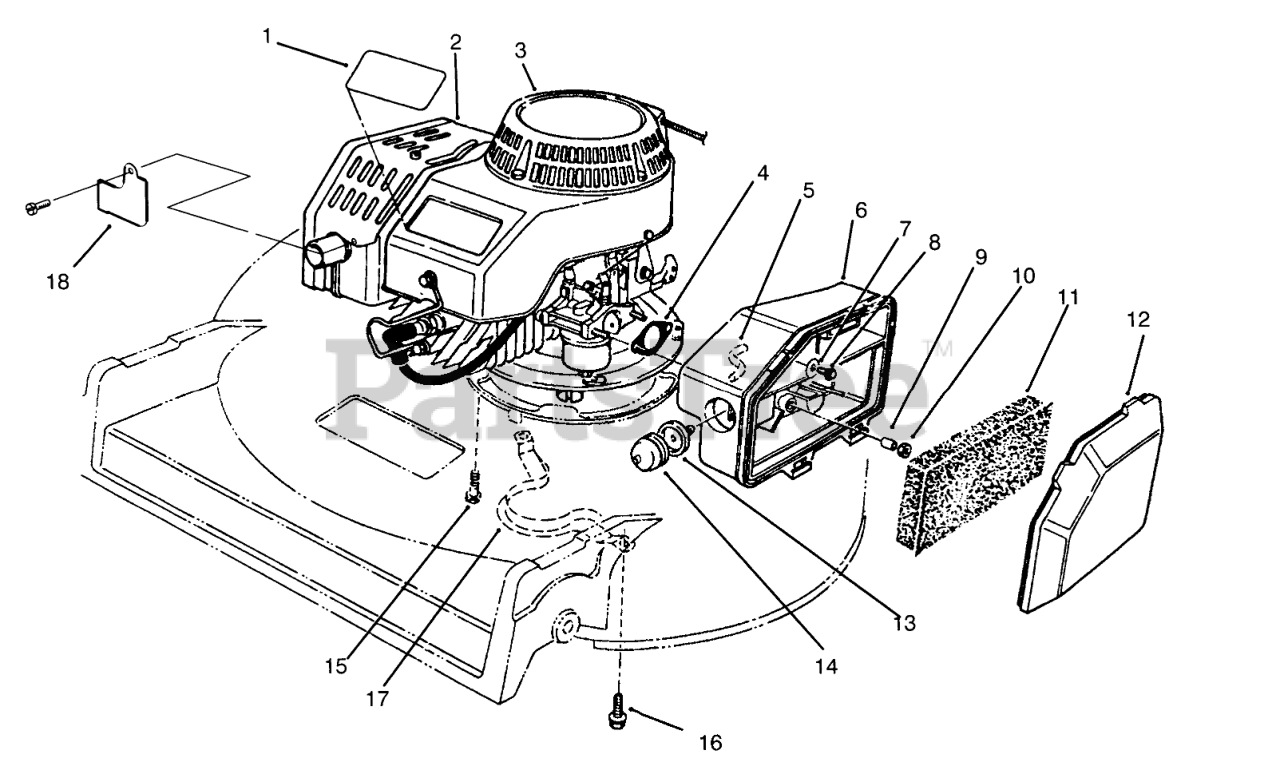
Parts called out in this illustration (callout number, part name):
1	DECAL - PROLINE
2	ENGINE ASM - BBC 2 CYCLE
3	DECAL-2 CYC RECOIL COMM
4	GASKET-AIR CLEANER
5	HOSE-PRIMER
6	BODY-AIR CLEANER
7	WASHER-FLAT
8	SCREW-HH
9	SPACER
11	ELEMENT-AIR CLEANER
12	COVER-AIR CLEANER
13	BODY-PRIMER
14	BULB-PRIMER
15	SCREW-HHF
16	SCREW-HWHTF
17	Guide-Belt
18	EXTENSION-MUFFLER GUARD
